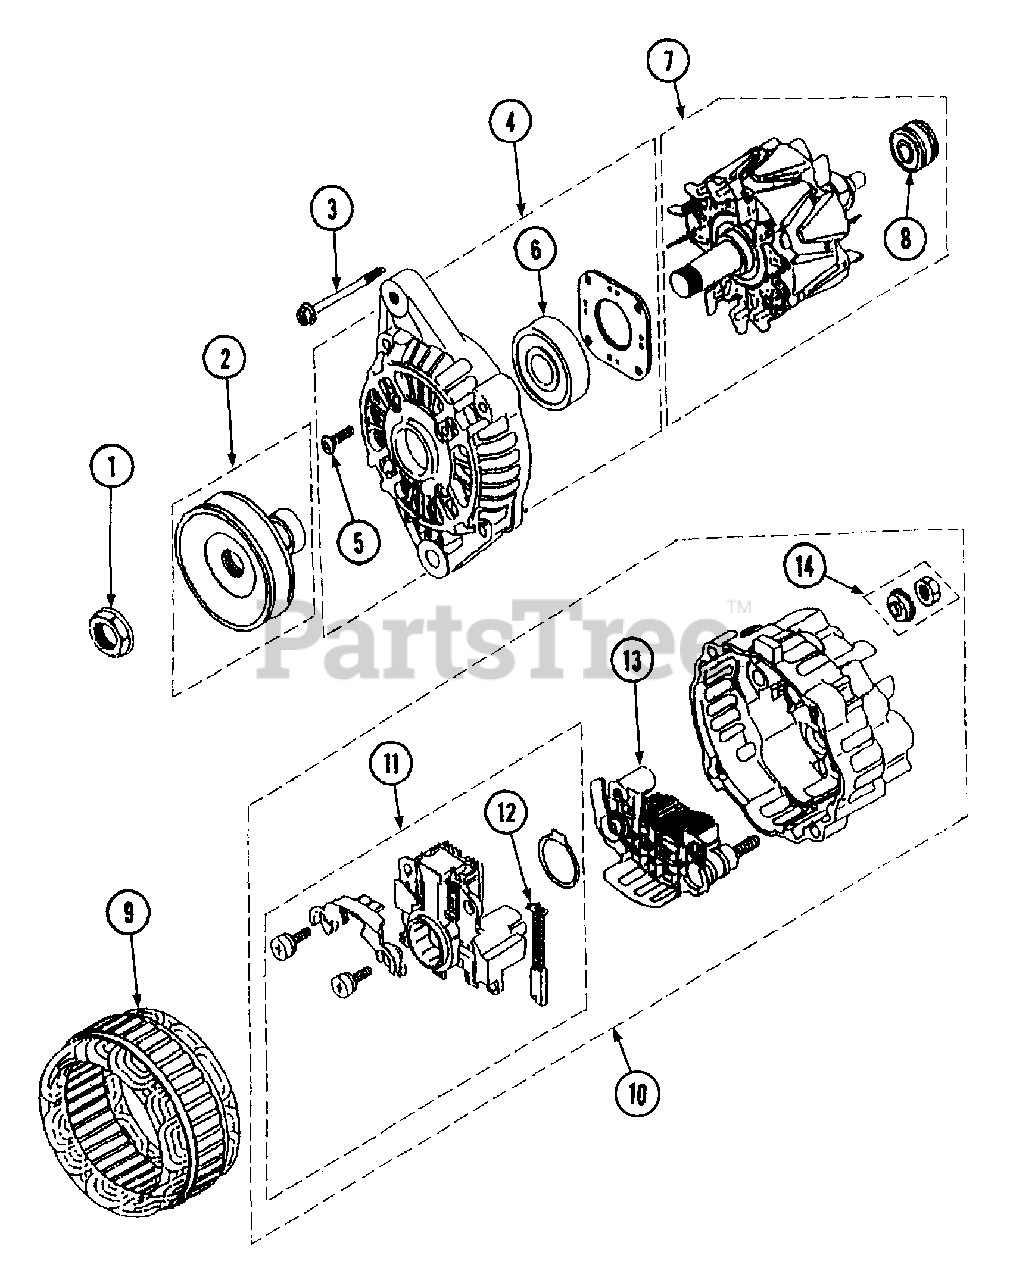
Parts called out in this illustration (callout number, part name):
3	Bolt Set
4	Bracket Ass'y., Front
6	Bearing, Front
7	Rotor Ass'y.
8	Bearing, Rear
9	Stator Ass'y.
10	Bracket Ass'y., Rear
11	Regulator Set
12	Brush
13	Rectifier Ass'y.
14	Nut Set
